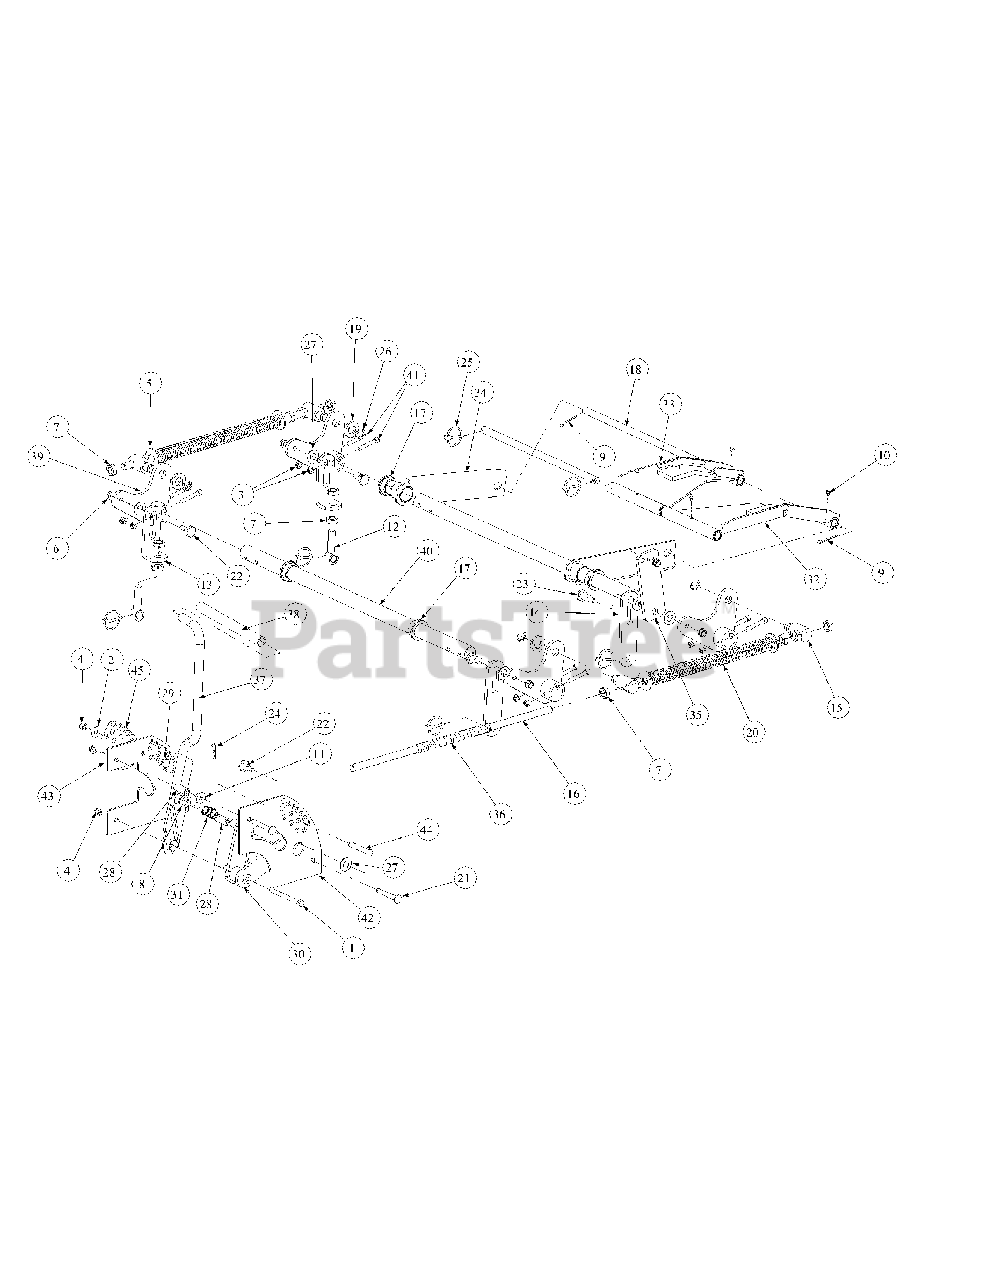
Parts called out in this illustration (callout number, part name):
1	Hex Cap Screw, 3/8-16, 3.75
2	Flat Washer, 3/8
3	Nut, 5/16-18, Nylock
4	Nylock Insert Lock Nut, 3/8-16
5	Flat Washer, 5/8
6	Hex Nut, Flange Lock, 3/8-16
7	Jam Nut, 5/8-11
8	Flat Washer, .06, .776, 1.25
9	Cotter Pin, 3/16 x 1-1
10	Grease Fitting, 1/4-28 x 3/16
11	Idler Washer
12	Eye Bolt, 5/8ID
13	Eye Bolt Mount Link, 5/8 ID
14	Deck Link
15	Ferule Lift
16	Lift Connector Rod
17	Hex Flange Bearing, 1.25 ID
18	Front Lift Link, Rod Mount
19	Spacer, .812 ID x .268 Lg.
20	Lift Compression Spring
21	Carriage Bolt, 3/8-16, 2.75
22	Shoulder Screw, 0.625 OD x .437 Lg.
23	Shoulder Screw, 0.625 OD x .830 Lg.
24	Cotter Pin, .148 x 3.00
25	Linch Pin, 3/16 Dia.
26	E Clip, 3/4 Dia.
27	Nylon Flat Washer, 5/8
28	Spacer, .39 ID x .63 OD x 1.442
29	Shoulder Screw,.50 OD x 0.27
30	Lift Pivot Assembly
31	Lift Handle Spring
32	Bearing Lift Brace Assembly, Right Hand
33	Bearing Lift Brace Assembly, Left Hand
34	Front Frame Strut Assembly
35	Lift Link Adjustment
36	Hose, 5/8 ID 13/16 OD, 8" LG
37	Lift Handle Assembly
38	Lift Handle Grip
39	Bellecrank Weldment Assembly
40	Deck Lift Shaft
41	Socket Head Cap Screw, 5/16-18 x 2
42	Outer Lift Index Plate
43	Inner Lift Index Plate
44	Clevis Pin,.438 Dia. x 2.625 Lg.
45	Decal Height Indicator
